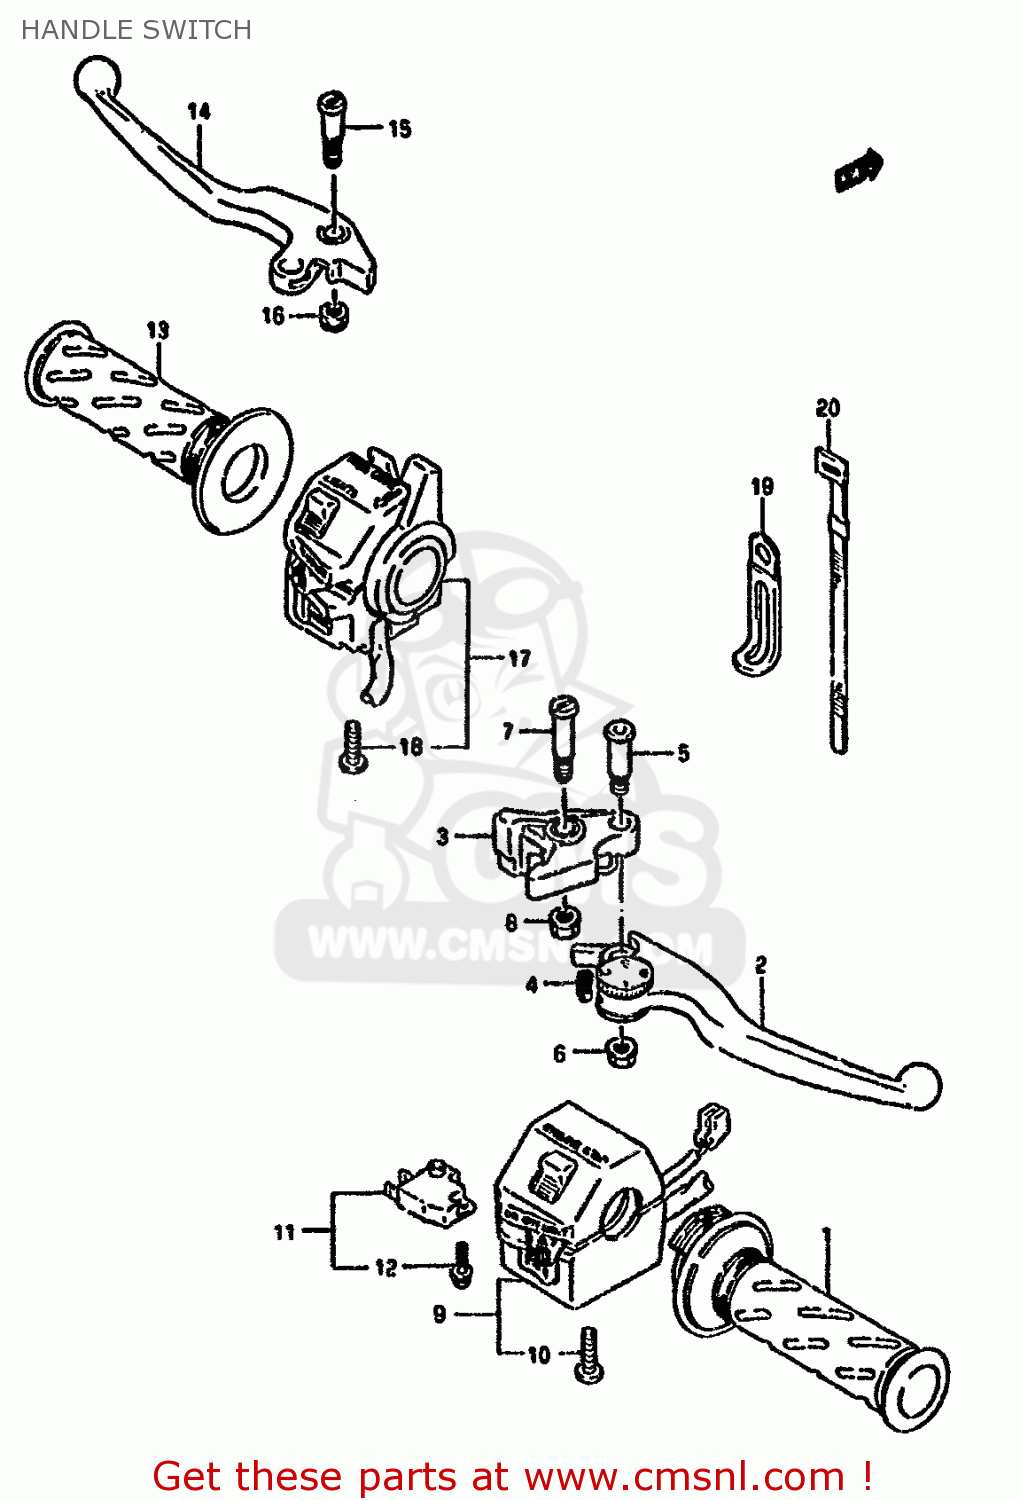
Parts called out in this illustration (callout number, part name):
1	GRIP,THROTTLE
2	LEVER,ADJUST
3	KNOCKER
4	SPRING
5	BOLT,LEVER
6	NUT
7	BOLT,LEVER PIVOT
8	NUT 6MM
9	SWITCH ASSY,HANDLE RH
10	SCREW, 5X45
11	SWITCH ASSEMBLY,STOP
12	SCREW
13	GRIP,LEFT
14	LEVER,CLUTCH (SILVER)
15	BOLT,LEVER
16	NUT
17	SWITCH ASSEMBLY,HANDLE,LEFT
18	SCREW, 5X45
19	CLAMP
20	CLAMP(L:120)
